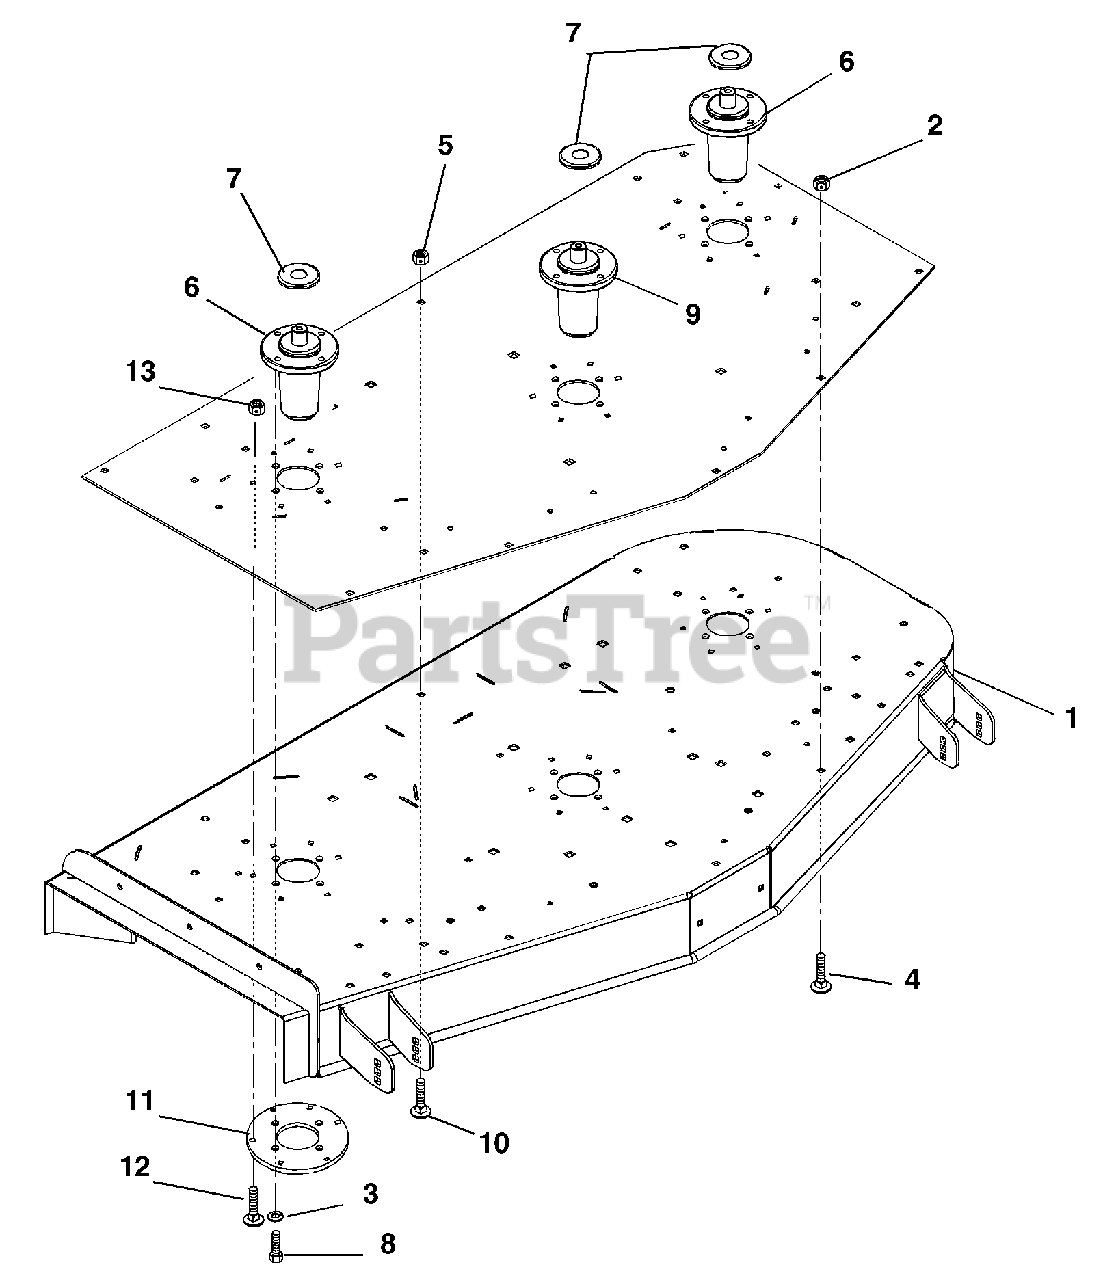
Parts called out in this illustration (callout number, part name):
1	Weldment, 72" Deck (Side Discharge)
2	Plate, 72" Reinforcment
3	Washer-Locking .38 x .094
4	Bolt-Round Head Square Neck .38-16 x 2.75 Grade 5
5	Nut-Locking-Nylon .38-16
6	Assembly, Spindle L-Hub
7	Slinger-Dust
8	Bolt-Hex .38-16 x 1.00 Grade 5
9	Spindle Assembly (Center)
10	Bolt-Round Head Square Neck .38-16 x 1.00 Grade 2
11	Plate, Spindle Reinforcement (035, 036)
12	Bolt-Round Head Square Neck .38-16 x 1.00 Grade 5
13	Nut-Locking-Center .38-16
